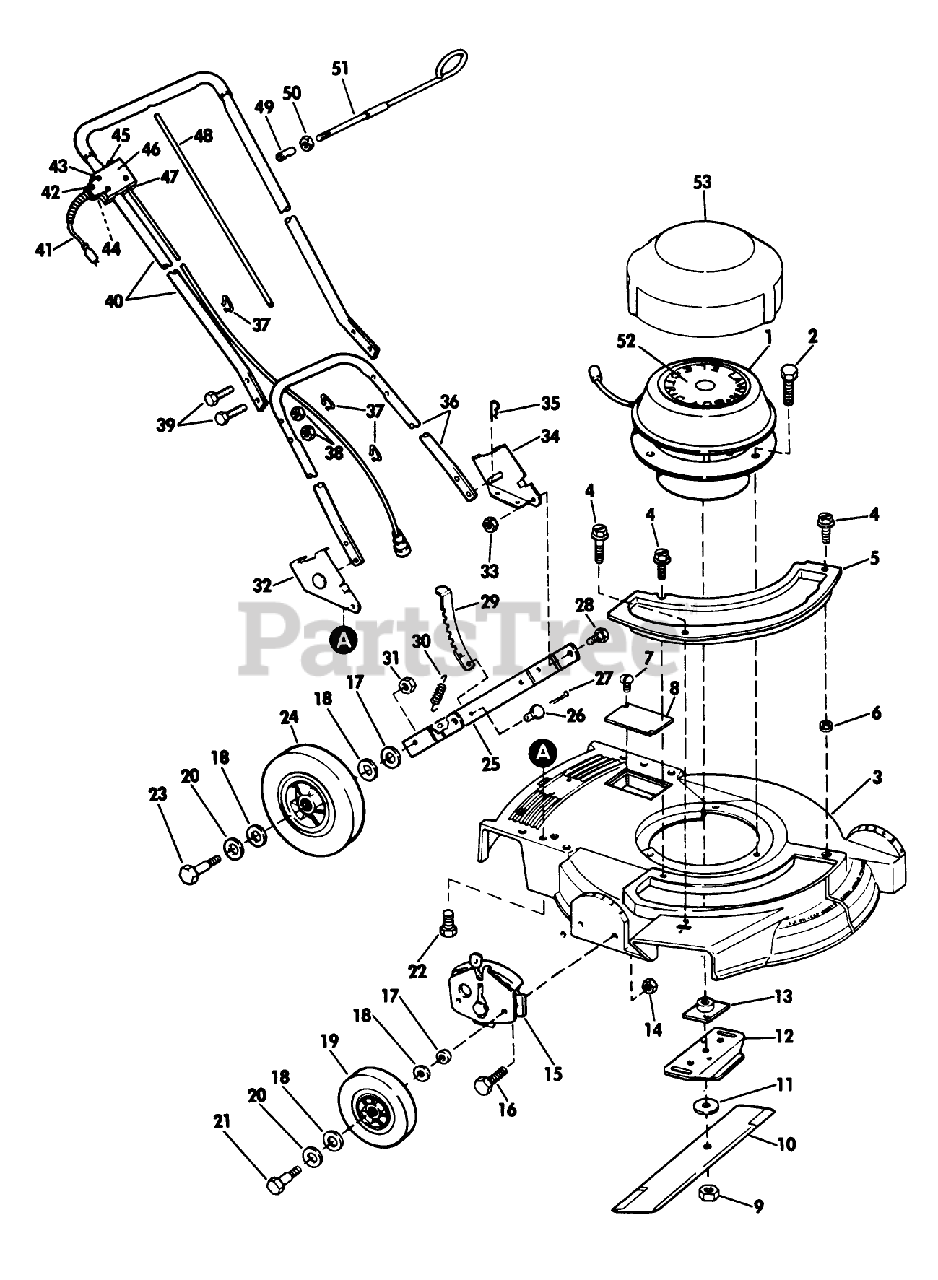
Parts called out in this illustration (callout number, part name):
2	SCREW
4	SCREW SEMS TRM HEX HD
9	NUT-BLADE
11	WASHER
13	PLATE AND COLLAR ASM
14	NUT
17	WASHER WROUGHT
18	WASHER
20	SPACER
21	BOLT WHEEL
23	BOLT
28	BOLT-SHOULDER
30	SPRING N.A.S
31	LOCKNUT
33	NUT
35	HAIR PIN
39	SCREW
42	Screw-Ground
44	NUT S
